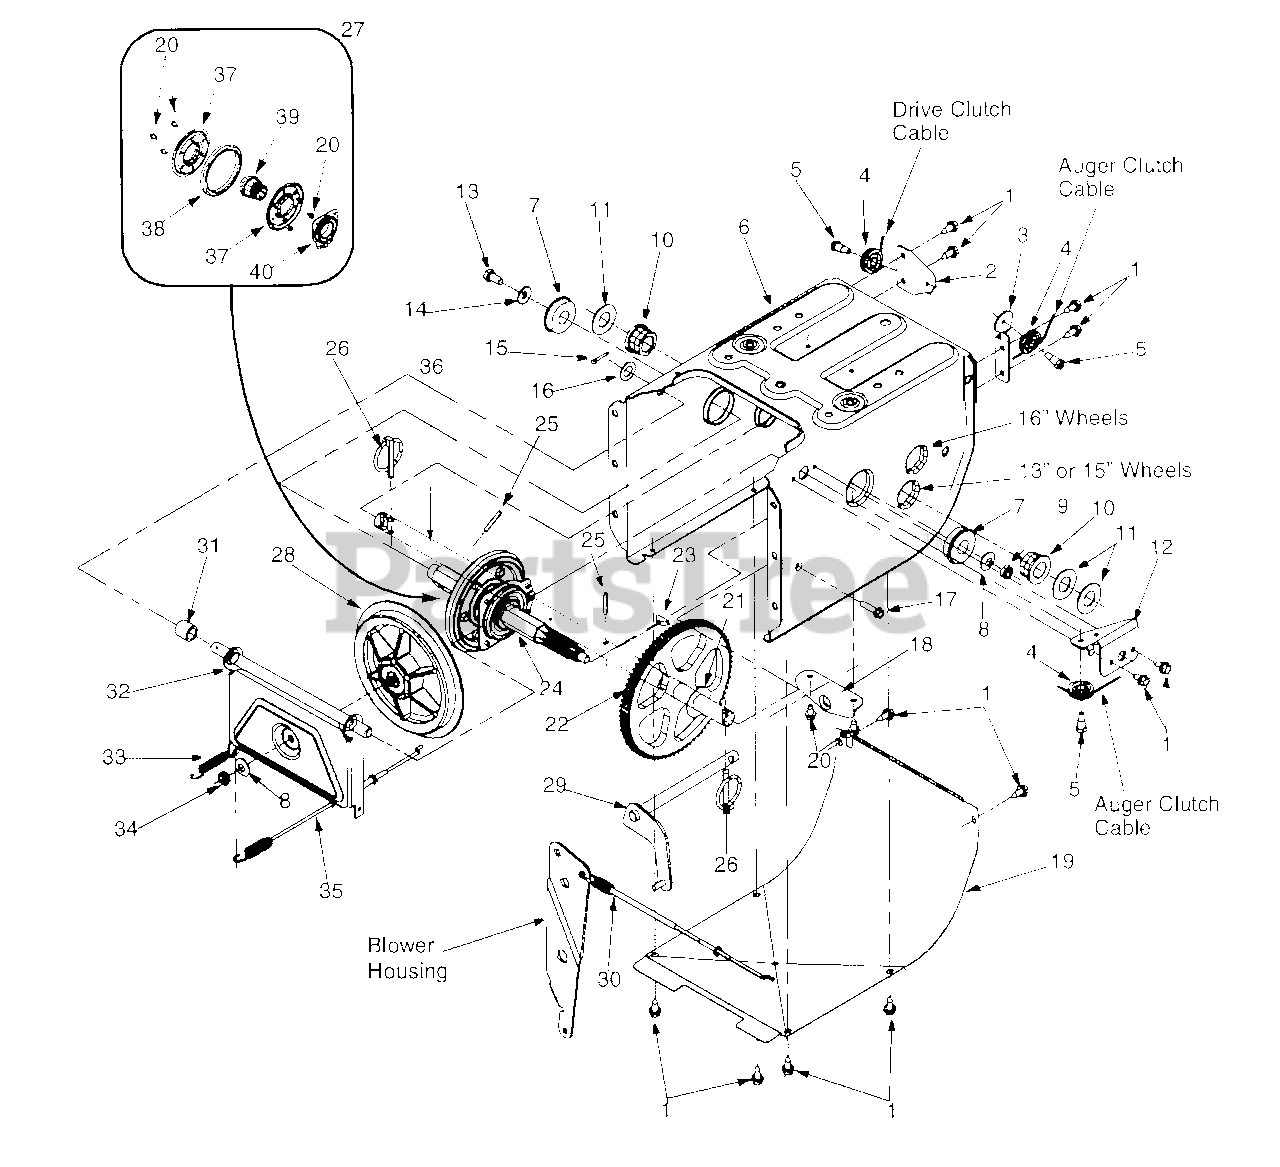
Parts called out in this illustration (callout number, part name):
1	Hex Screw
5	Hex Screw 1/4-28
8	Bell Washer
9	Lock Jam Nut
10	Hex Flange Bearing
11	Flat Washer
14	Bell Washer .340 ID x .872 OD
15	Cotter Pin
16	Flat Washer .536 ID x .930 OD
17	Hex Washer Screw 1/4-20
21	Flat Washer .760 ID x .50 OD
24	7-Tooth Shaft
25	Roll Pin
26	Klik Pin
27	Friction Wheel Assembly
28	Friction Disc Wheel
29	Wheel Shift Rod Assembly
30	Drive Cable
34	Jam Nut 3/8-24
35	Drive Cable
36	Axle 13" Wheels
37	Friction Plate
38	Friction Wheel Rubber
39	Friction Wheel Hub
40	Friction Wheel Bearing
